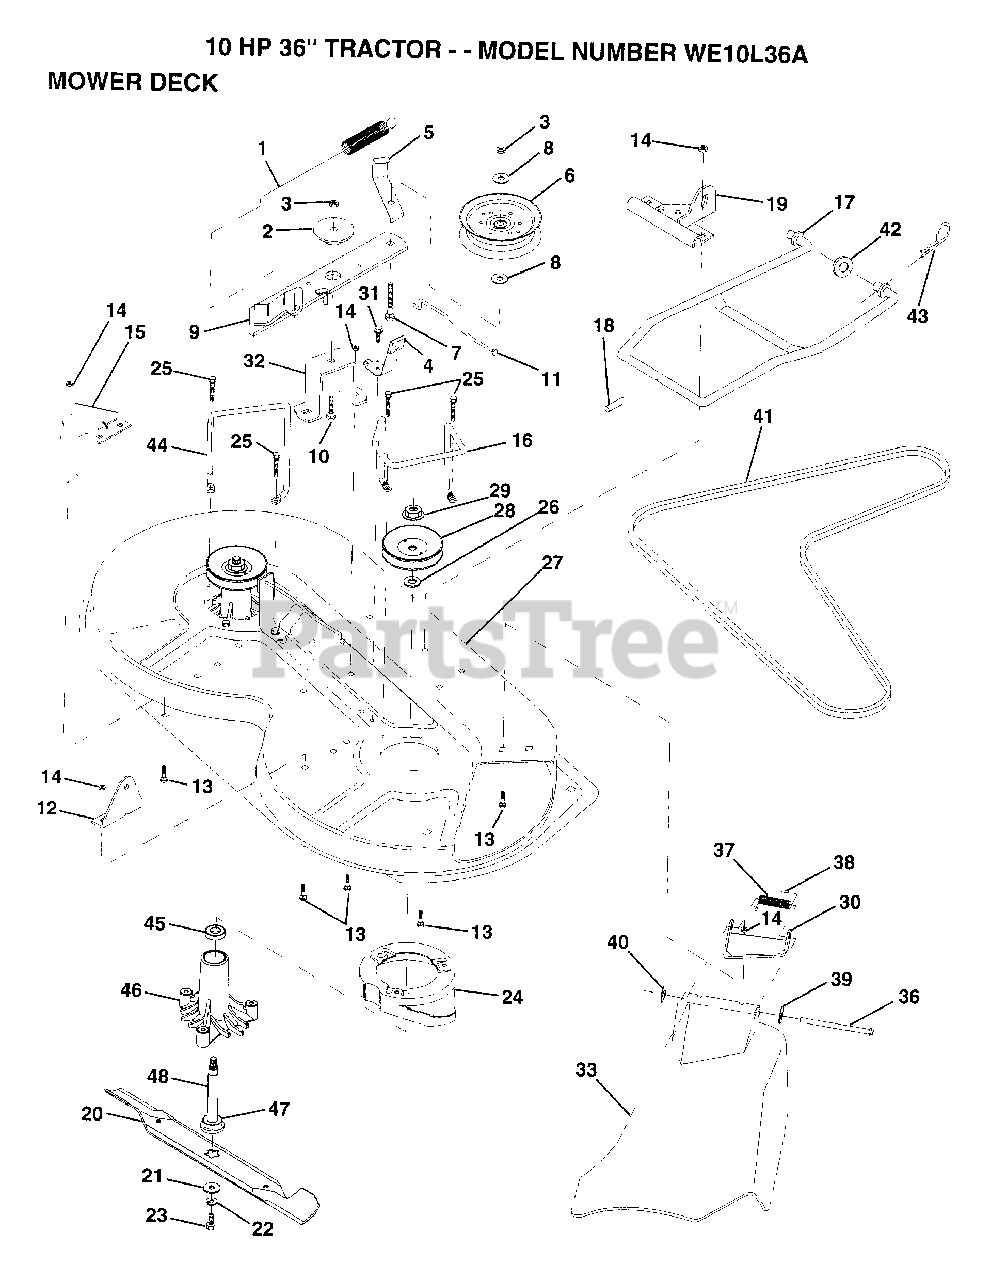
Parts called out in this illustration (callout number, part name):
2	SPACER RETAINER
4	BRAKE ASM
5	IDLER BELT GUIDE
6	PULLEY IDLER
7	BOLT
8	WASHER
10	BOLT D
11	BRAKE ROD
12	"BRKT,LIFT REAR"
13	BOLT
15	"BRKT,LIFT REAR LH"
17	MOWER LINK STAB
18	"PIN,GROOVE"
19	"BRKT,LINK STABILI"
20	"BLADE.36"" HIPERF"
21	WASHER BLADE
23	BLADE BOLT
26	WASHER
31	SCREW LT
32	"SUPT,IDLER ARM"
36	HINGE ROD
37	SPRING TORSION
38	CAP-SLEEVE LT
39	WASHER
40	NUT PUSH M
41	V-BELT.PRIM.78.5.
43	RETAINER.SPRING
45	BEARING
46	HSG ASM MANDREL
47	BEARING.BALL
